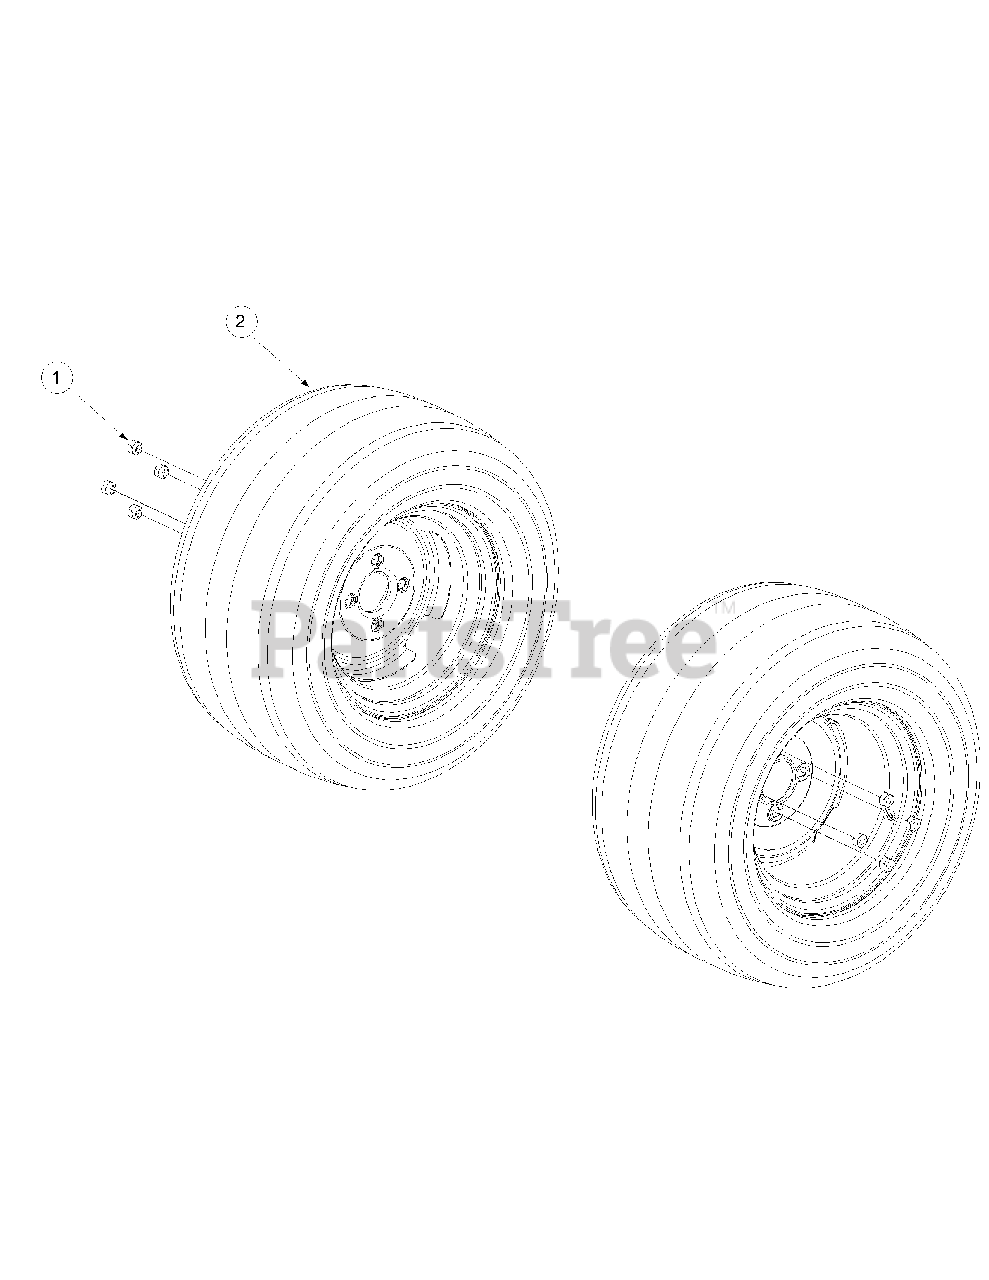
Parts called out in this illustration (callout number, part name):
1	Nut, Lug, 1/2-20
2	Wheel Assembly, 24 x 12.00-12, Beige Includes:
2	Tire, 24 x 12.00-12, Turf Master
2	Wheel Assembly, 24 x 12.00-12, Turf Saver
2	Tire, 24 x 12.00-12, Turf Saver
